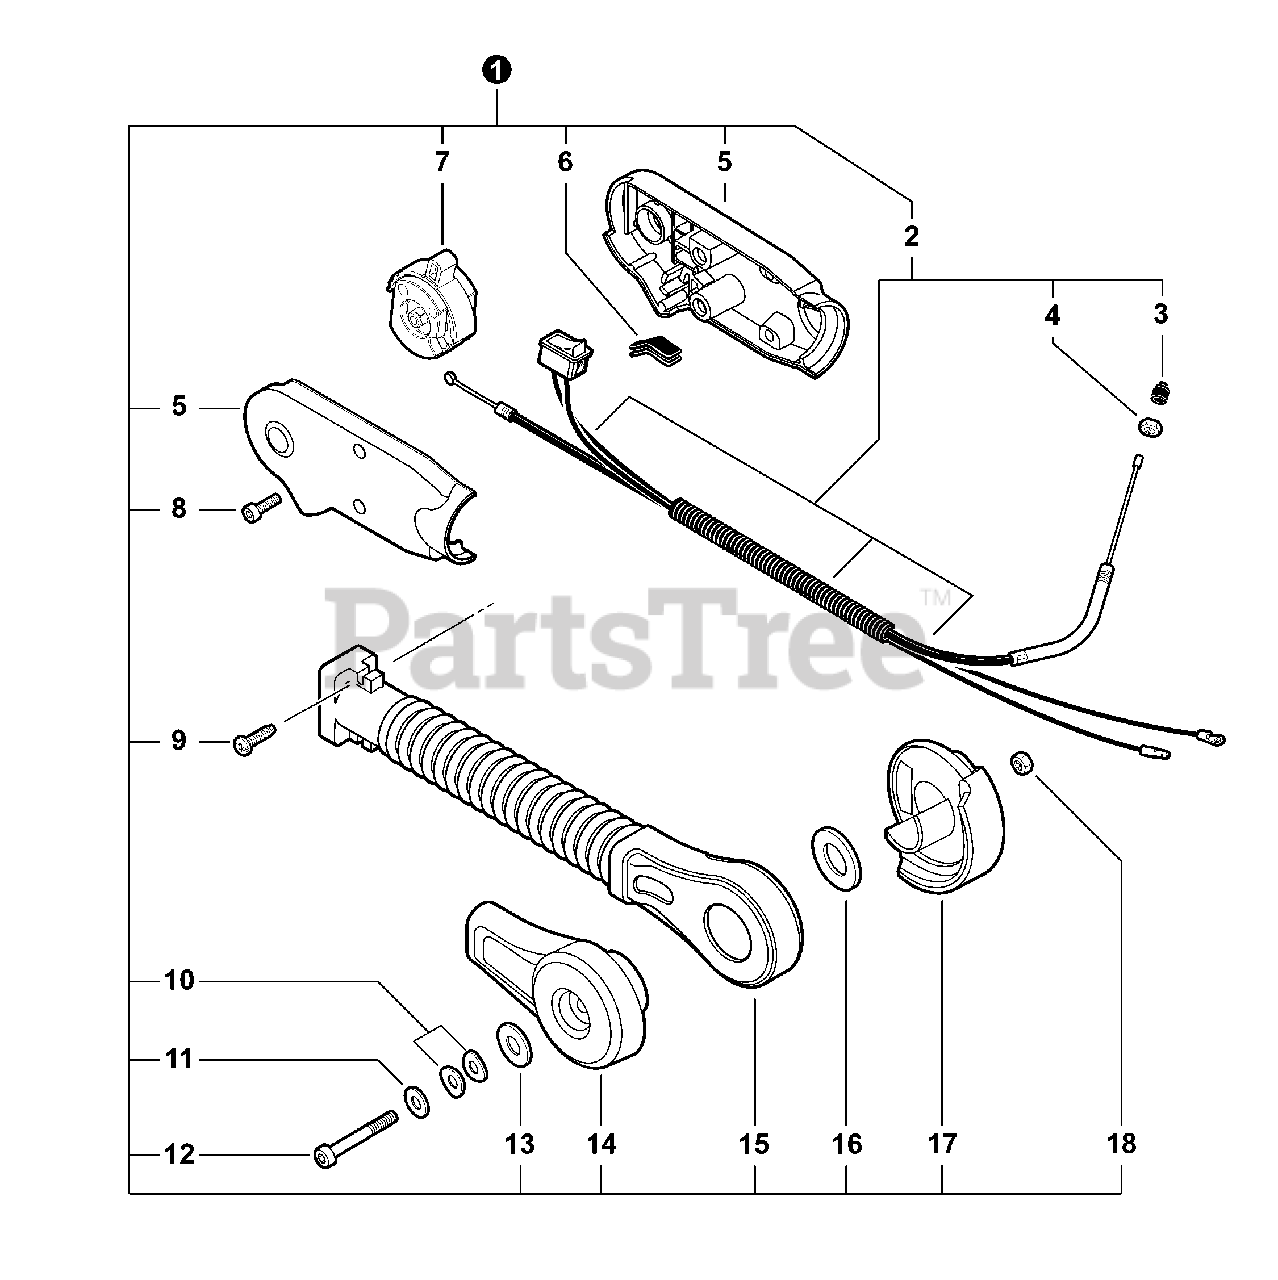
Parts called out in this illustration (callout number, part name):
1	HIP MOUNT THROTTLE CONTROL KIT
2	CONTROL CABLE ASSY
3	CAP, DUST
4	LOCKNUT - 6
5	CONTROL HANDLE KIT
7	THROTTLE CONTROL ASSY
8	SCREW - 5×16
9	SCREW - 5×20
10	WASHER - SPRING
11	WASHER - 6
12	SCREW - 6×75
13	WASHER - 6
14	BRACKET, ARM - OUTER
15	ARM, THROTTLE CONTROL
17	BRACKET, ARM - INNER
18	LOCKNUT - 6
